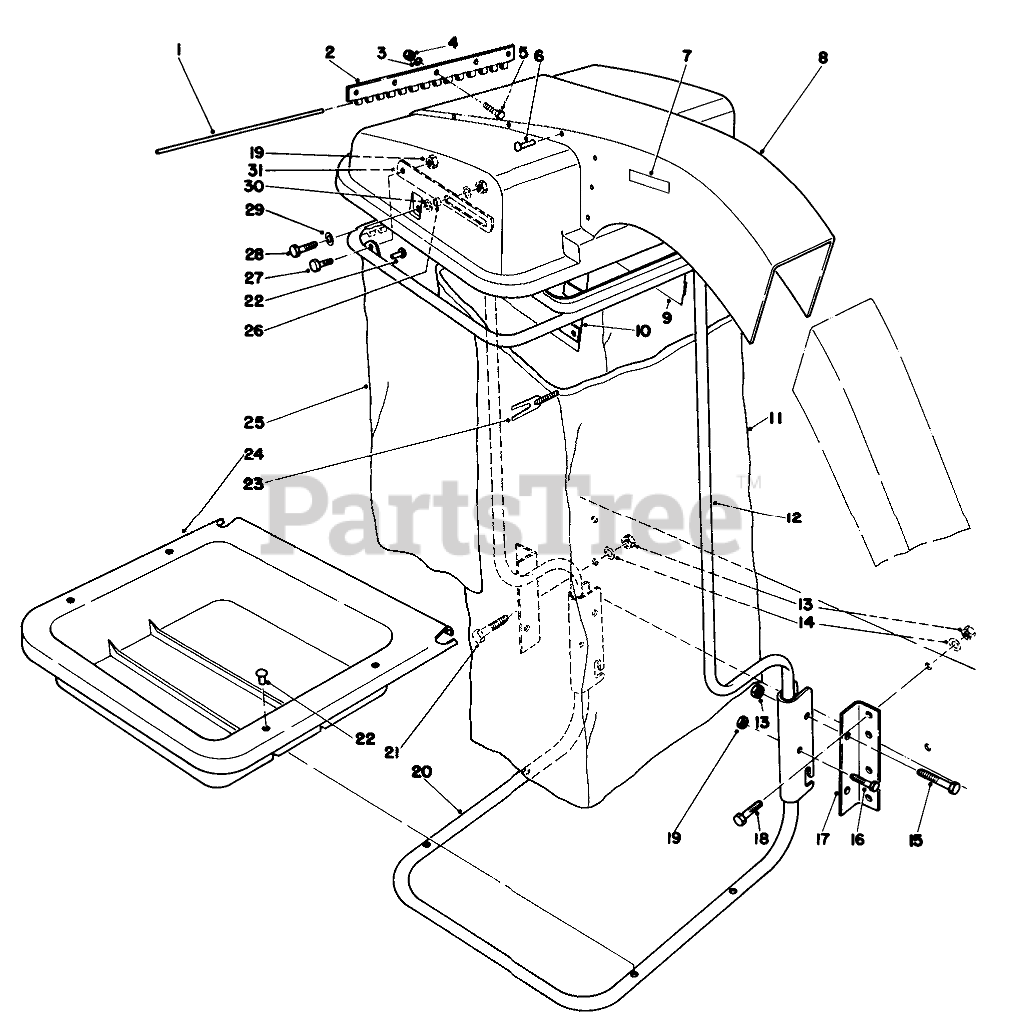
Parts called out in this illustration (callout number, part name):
1	HOOD HINGE PIN
2	Hinge Half
3	WASHER-FLAT
4	NUT-LOCK, NI
6	RIVET-BLIND
7	Decal-Caution
8	Hood Assembly (Incl. Ref. #2-7 & 9-10)
9	Screen Left Hand
10	Screen Right Hand
11	BAG-CLOTH, 32"
12	Support Tube Assembly-Upper (Incl. Ref. #22 & 25)
13	NUT-LOCK, CONE
14	WASHER-FLAT
15	SCREW-HH
16	SCREW-HH
17	BRKT-FRAME B
18	SCREW-HH
19	NUT-LOCK, CONE
20	Support Tube Assembly-Lower (Incl. Ref. #22 & 24)
21	SCREW-HH
23	BAG CORD FASTENER
24	Tray-Lower
25	Skirt-Bagging Frame
26	SPACER - PIVOT ARM
27	SCREW-HH
28	SCREW-HH
29	WASHER-FLAT
30	WASHER-FLAT
31	Stop-Hood
